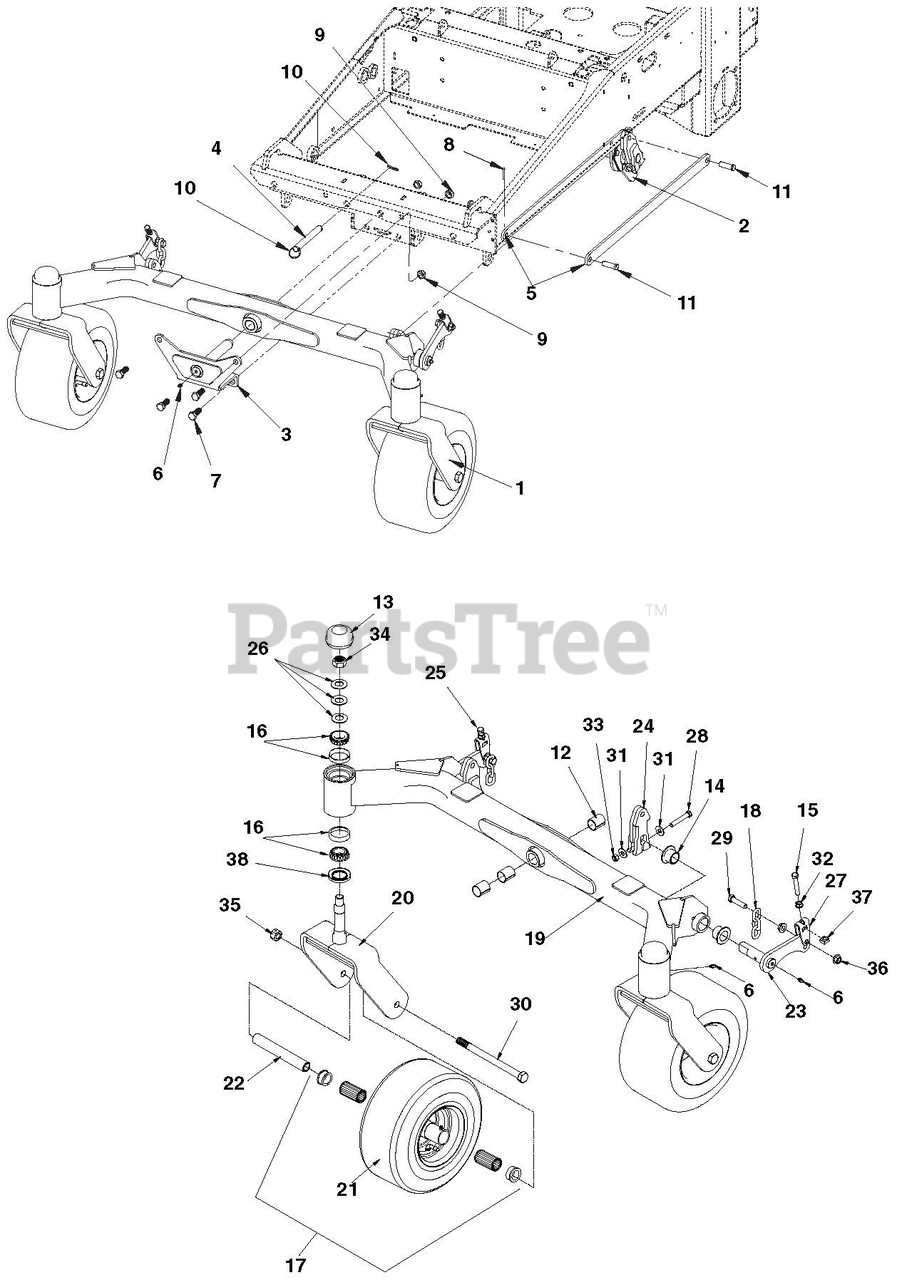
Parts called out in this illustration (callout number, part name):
1	Front Axle Frame Assembly
2	ASSY, REAR LIFT ROD
3	WLDT, FRONT AXLE BRACKET
4	PIN, MFG .625X5.00X4.38 XDRL Y
5	PLATE, CONNECTOR LINK
6	FTG, 1/4-28 STRGT GREASE ZERK
7	BOLT, 1/2-13X1.25 HEX 5 Y
8	RING, RUE .500 X .062 X 1.420
9	LOCKNUT, 1/2-13 CROWN Y
10	RING, WIRE - .080 X 1.25
11	PIN, CVS .500X1.50X1.27 Y
12	BEARING, SLV 1.00X1.13X1.25
13	CAP, SPINDLE
14	BRG, FLG 1.00X1.25X.944
15	BOLT, 3/8-16X2.25 HEX 5 FLTD Y
16	BRG ASSY, 1IN DIA SPINDLE
17	KIT, BEARINGS & CAPS 1.00"
18	CHAIN, IMPLEMENT HOLD (3-LINK)
19	WLDT, FRONT AXLE
20	WLDT, Z FRONT WHEEL FORK
21	ASSY, TIRE & RIM - 13/6.50X6
22	TUBE, FRONT TIRE AXLE
23	WLDT, LH FRONT PIVOT
23	WLDT, RH FRONT PIVOT
24	WLDT, FRONT PIVOT CLAMP
25	ASSY, DECK LEVELER
26	WASHER, .750X1.50X.072 BLVL U
27	LINK, U-BRACKET
28	BOLT, 3/8-16X2.25 HEX 5 Y
29	BOLT, 7/16-14 X 2.00 HEX5SPC Y
30	BOLT, 5/8-11X8.50 HEX 5 Y
31	WASHER, .375 REG FLAT Y
32	LOCKNUT, 3/8-16 WHIZ Y
33	LOCKNUT, 3/8-16 CROWN Y
34	LOCKNUT, 3/4-16 CROWN PL
35	LOCKNUT, 5/8-11 CENTER Y
36	LOCKNUT, 7/16-14 WHIZ Y
37	NUT, 3/8-16 SQUARE Y
38	SEAL, BRG 1.00 ROLLER
